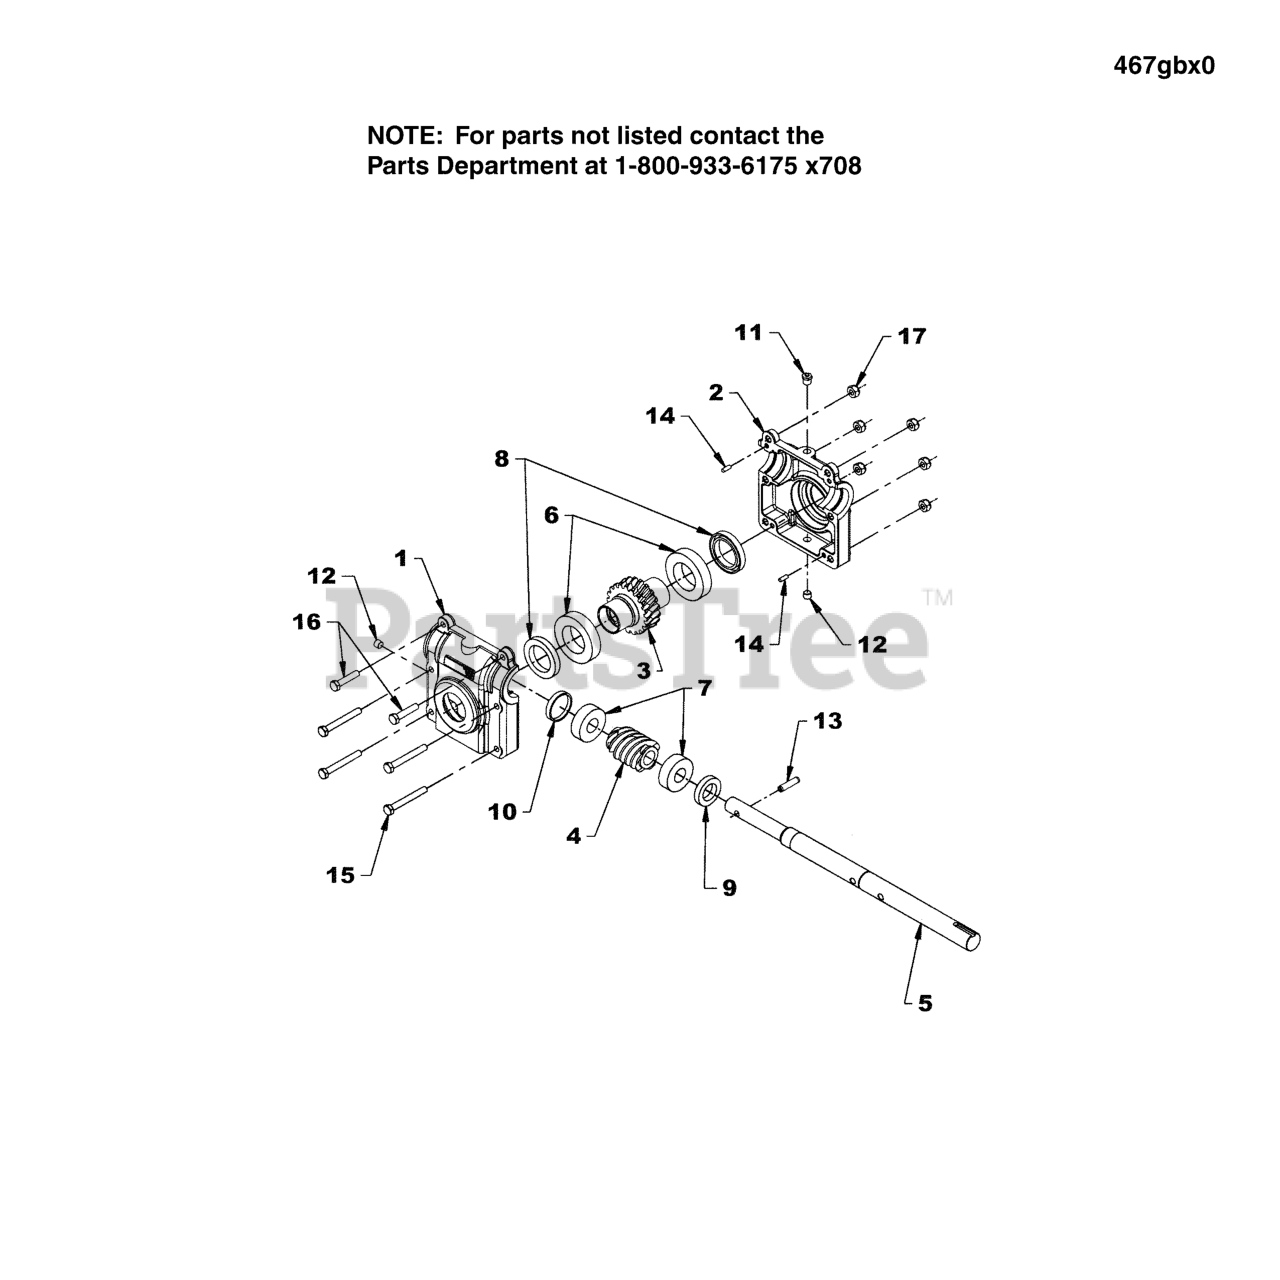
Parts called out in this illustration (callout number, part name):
1	Left casing
2	Right casing
3	Gear
4	Worm
5	Driving shaft
6	Bearing
7	Bearing
7A	Seal kit (item 8 and 9)
8	Seal
9	Seal
10	Cap
11	Breather 1/8" NPT, 5 PSI, PTD
12	Plug 1/8" NPT, PTD
13	Spring pin 5/16" dia. x 1 1/4" lg.
14	Dowel pin 3/16" dia. x 1/2" lg.
15	Hex. bolt 5/16" NC x 2 1/2" lg., PTD
16	Hex. bolt 5/16" NC x 1 1/2" lg., PTD
17	Nylon insert locknut 5/16" NC, PTD
